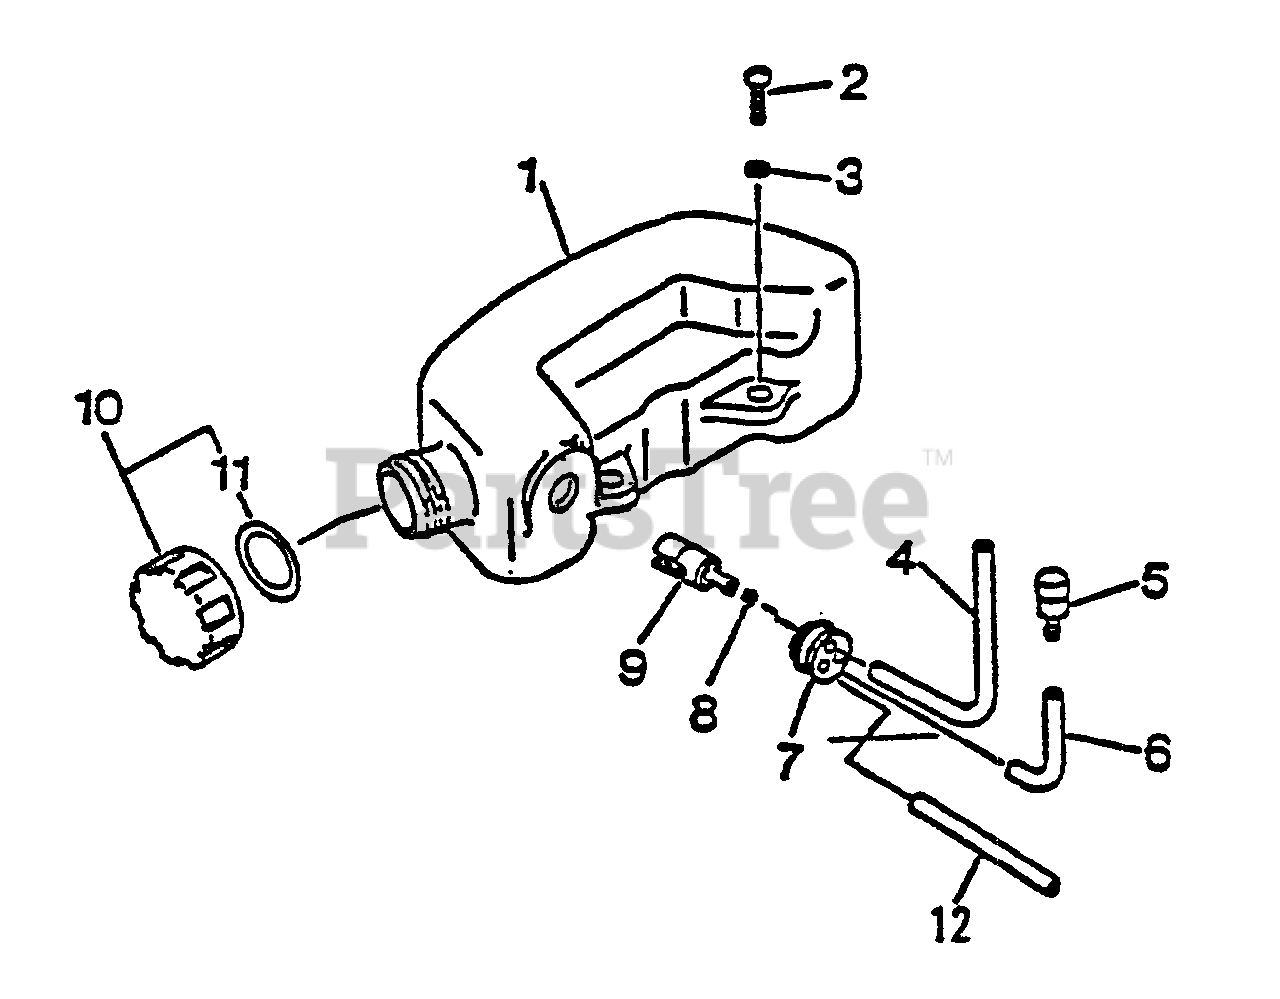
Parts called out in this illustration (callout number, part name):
1	TANK, FUEL
2	SCREW 5×16
3	WASHER 5.5×12×0.8
4	PIPE, FUEL
5	VENT ASSY
6	PIPE, FUEL RETURN 3×6×70
7	GROMMET, FUEL
8	CLIP 6 MM
9	FILTER, FUEL
10	CAP ASSY
11	GASKET, FUEL CAP
12	PIPE, FUEL RETURN 3×6×110
